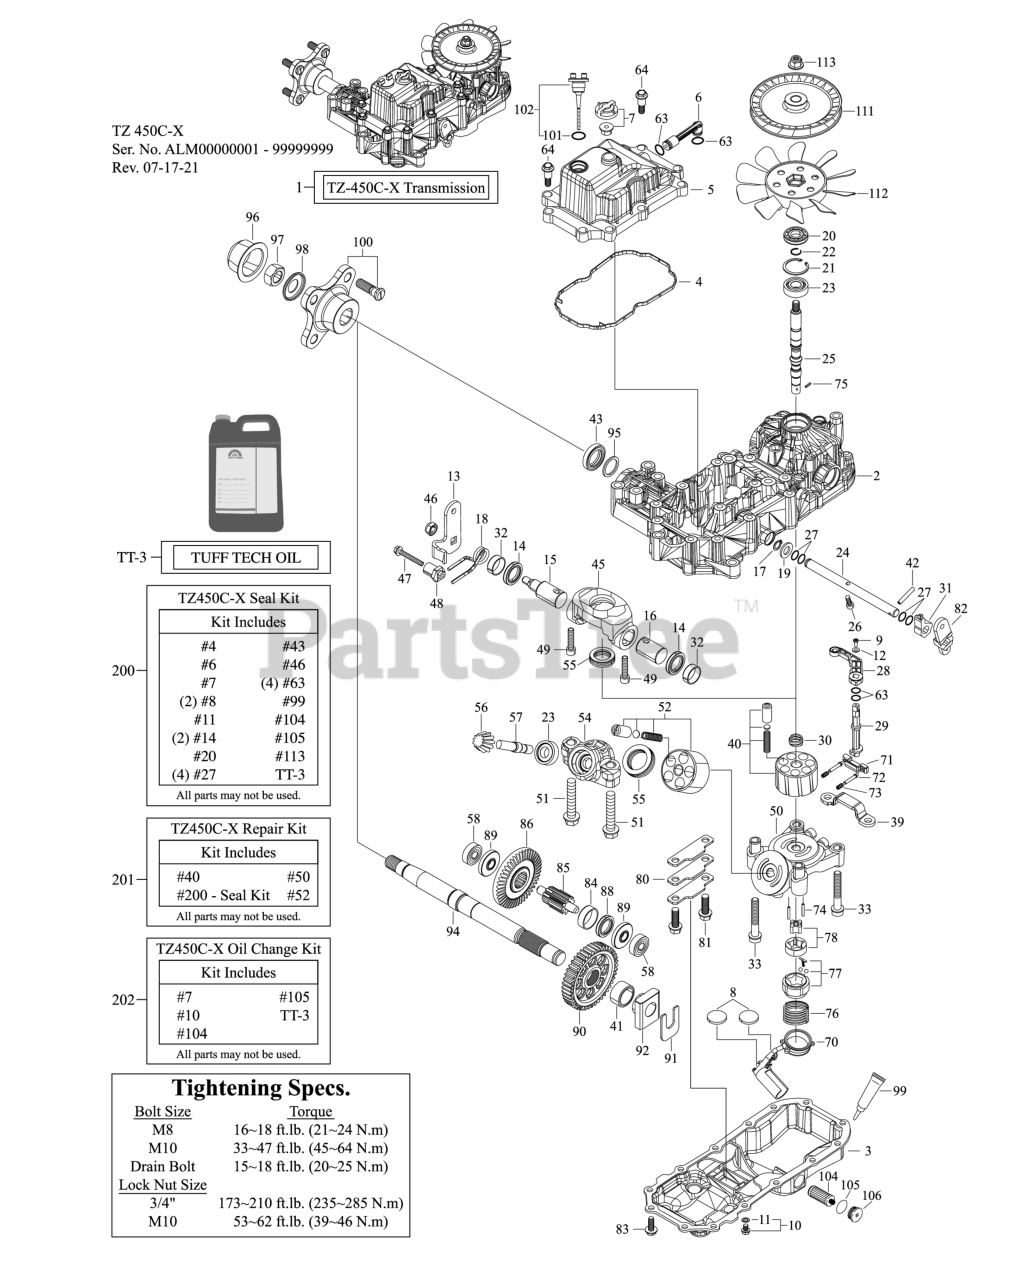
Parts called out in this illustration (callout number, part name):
1	Transaxle - Tuff Torq, LH - SZL
2	Upper Housing X
3	Lower Housing Fy
4	Square Seal
5	Top Cover A
6	Bypass Piping
7	Vent Valve
8	Magnet 28 * 3.5
9	Screw 4.0*8
10	Drain Bolt Kit
11	Washer Seal 10
12	Washer 4.5*10*1
13	Control Lever L
14	Seal, Tc253506
15	Control Shaft
16	Control Shaft Short
17	Snap Ring
18	Torsion Spring
19	Washer 12
20	Oil Seal 15*35*07
21	Snap Ring C 35
24	Brake Shaft
25	Pump Shaft C
26	Socket Bolt 6*16
27	O-Ring 1a P12
28	Bypass Lever
29	Bypass Shaft
30	Pump Spring
31	Brake Fork 20 Cr
32	Control Bush Lfb2510
33	M10 * 65 Bolt
39	Check Stopper Pfg
40	Cylinder Block Kit / Order Repair Kit
41	Bushing 25.4
42	Spring Pin 5 * 32
43	Seal Tc284008
45	Swashplate
46	Lock Nut 10
47	Bolt 6*45
49	Bolt 8 * 35
50	Centercase Cp / Order Repair Kit
51	Bolt 12*65
52	Cylinder Block Kit(Motor / Order Repair Kit
54	Motor Housing
55	Thrust Bearing
56	Motor Gear S
57	Motor Shaft
58	Bearing 6201 Cn
63	0-Ring 1a P10a
64	Tapping Bolt 8*30
70	Bracket Assy Fts
71	Bypass Guide
72	Bypass Pin
73	Bypass Spring
74	Pin 3.0 * 18
75	Pin 2.5* 9.8
76	Charge Spring
77	Pump Case
78	Rotor Set
80	Final Plate
81	Bolt 10 * 30
82	Brake Arm
83	Tapping Screw 8 * 20
84	Final Pinion Collar
85	Final Pinion Shaft
86	Reduction Gear S
88	Reduction Collar
89	Reduction Collar
90	Final Gear Sv
92	Bushing 25.4
94	Axle Shaft T
96	Nut Cap
97	Lock Nut 3/4-16
98	Flange Spacer
100	Flange Assy.
101	O-Ring 1a P16
102	Dipstick Assy.
104	Filter
105	O-Ring 1a 24040
106	Cap 40
111	Pulley,5.5
112	Fan
113	Lock Nut 10
200	Seal Kit Tz-450
201	Repair Kit Tz-450 C
202	Tz 450 Oil Change Kit
TT-3	Tuff Tech Oil (3 Liter Bottle)
